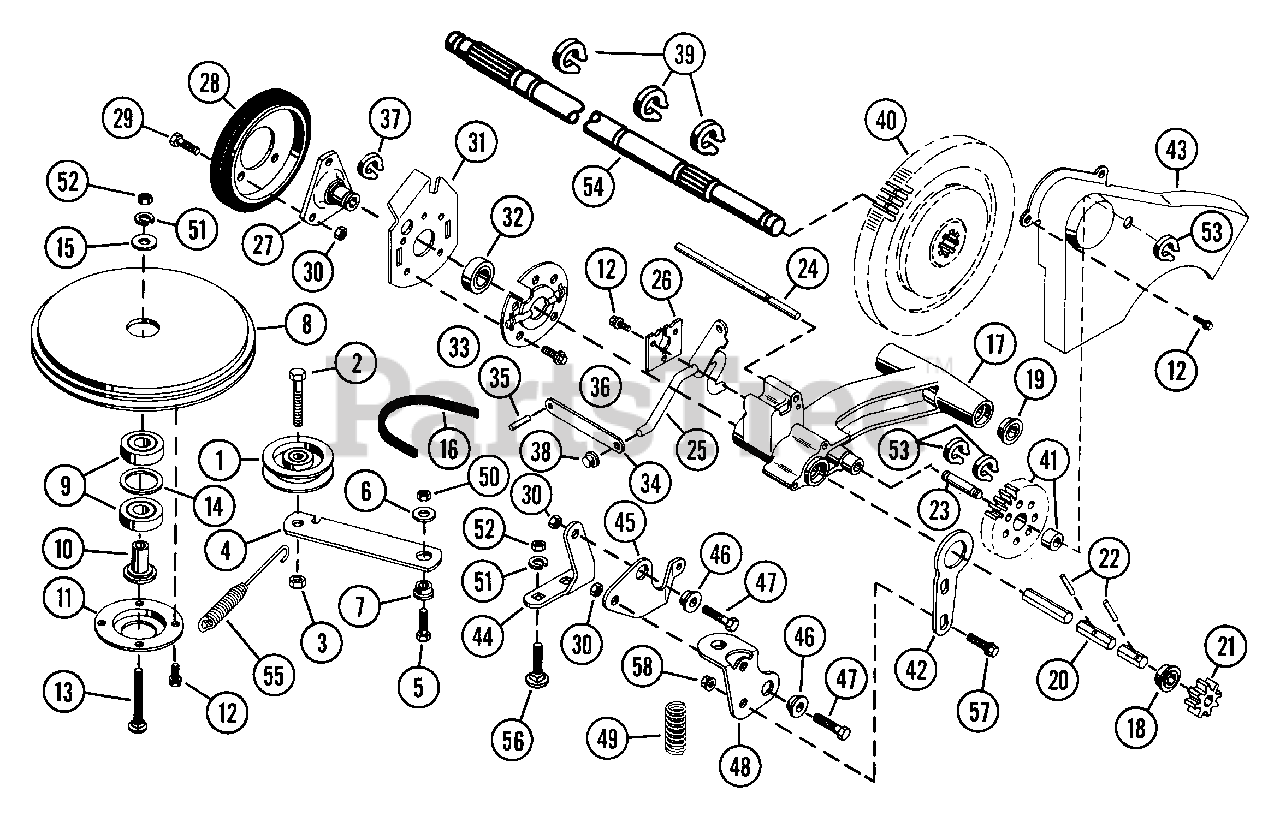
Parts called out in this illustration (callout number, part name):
1	IDLER-FLAT 1.88 X .38 NWHAMSHR
2	BLT-HEX .38-16X1.50 PL GR2
3	NUT-LK-CTR .375-16 GR A PL
4	IDLER ARM
5	BLT-HEX .31-18X.75 PL GR2
6	WSHR-FL-STL .323X.625X.062 PL
7	BSHG, FLG .325X.499X.26X.88
8	FRICTION SHEAVE
9	BRG-BALL .625X1.375X.44
10	SPINDLE - BEARING
11	RETAINER - BEARING
12	SCR-TAP 12-24X.50 HWH PL TR
13	BLT-RDHDSQNK .31-18X1.75 PL
14	WSHR-FL-STL 1.062X1.344X.032PL
15	WSHR-FL-STL .328X.875X.062 PL
16	V-BELT 3L 32.2
17	DRIVE MOUNT
18	BRG-RADIAL .562X1.38 HEX
19	BRG-BALL .750X1.50X.44
20	HEX SHAFT
22	PIN-ROLL .188X.88
23	SHAFT - IDLER
24	ROD - GUIDE
25	SHIFT ARM WELDMENT
26	RETAINER PLATE
27	FRICTION WHEEL HUB
28	FRICTION DISC
29	BLT-HEX .25-20X.50 PL GR2
30	NUT-LK-CTR .250-20 PL
31	BEARING PLATE
32	BRG-BALL 1.0X2.0X0188
33	BEARING RETAINER
34	SHIFT LINK
35	PIN-ROLL .125X.50
36	SCR-TAP 10-24X.375 HWH PL TR
37	RG-RTNG-EXT 1.00X.042
38	PUSH NUT, .25
39	RG-RTNG-EXT .750X.042
40	DIFFERENTIAL ASSEMBLY
41	IDLER GEAR ASSEMBLY
41	BRG-NEEDLE .500X.688X.625
42	CLUTCH COLLAR
43	GEAR COVER
44	MOUNTING BRACKET
45	CLUTCH ARM
46	BSHG-FLG .265X.437X.250X.750
47	BLT-HEX .25-20X.63 PL GR2
49	SG-COMP .086X.625X3.44
50	NUT-LK .312-18 GR A PL
51	WSHR-LK .312X.097 PL HVY
52	NUT-HEX .312-18
53	RG-RTNG-EXT .438X.035
54	REAR AXLE
55	SG-TENS .043X.44X3.31 WLD 5.8
56	BLT-RDHDSQNK .312-18X.62SHTPL
57	BLT-SERHFWH .25-20X.50 PL
58	NUT-LK-FLG .250-20 PL
